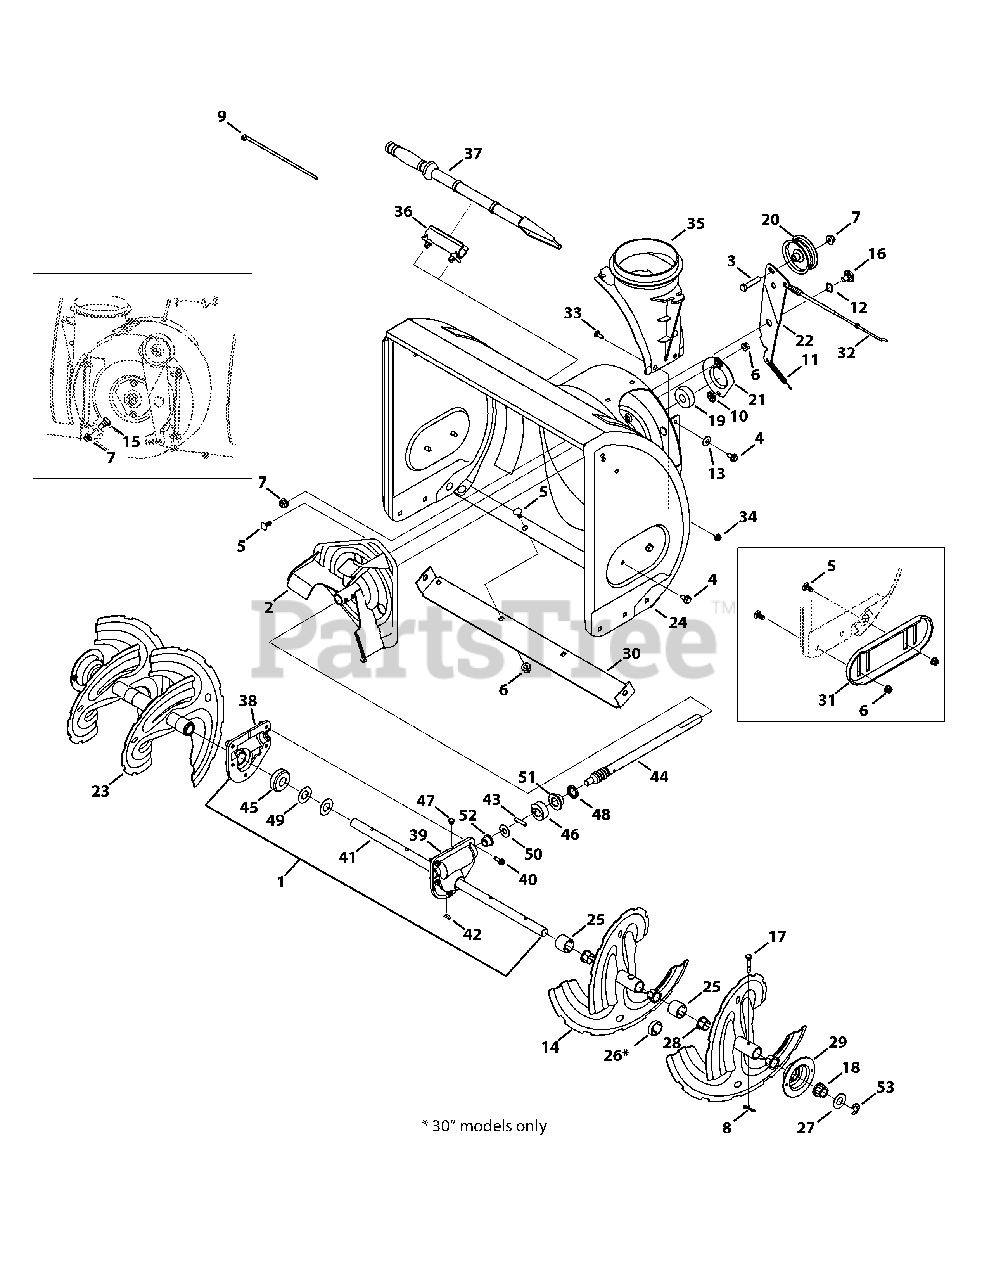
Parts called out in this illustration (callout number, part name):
1	Gearbox Ass'ly, 28", includes 38-52
2	Impeller Assembly, 12" Dia.
3	Hex Head Screw, 3/8-16 x 1.75
4	Screw, 5/16-18 x .750
5	Bolt, Carriage, 5/16-18 x .750
6	Nut, Flange lock, 5/16-18
7	Nut, Flange lock, 3/8-16
8	Bow-Tie Cotter Pin
9	Cable Tie, 7"
10	Nut, Push-on, .25 Dia.
11	Extension Spring, .38 x 4.59
12	Washer, Wave, .625 x .885
13	Washer, Bell, .340 x .872
14	Spiral Assembly, LH
15	Bolt, Shoulder, .496 x .336 x 3/8-16
16	Screw, Shoulder, .625 x .17 x 3/8-16
17	Shear Pin, .25 x 1.50
18	Hex Flange Bearing
19	Bearing, Ball, .75 x 1.85
20	Pulley, Idler, Flat, 2.75
21	Bearing, 1.85 ID
22	Auger Idler Bracket
23	Spiral Assembly, RH
24	Auger Housing Assembly, 28"
25	Spacer, 1.25 x .75 x 1.00
26	Spacer, 1.250 x .75 ID x 3/16 LG
27	Washer, Flat, .76 x 1.49
28	Bushing, Flange, .800 x .910
30	Shave Plate, 2.25 x 27.66
31	Deluxe Slide Shoe
32	Auger Drive Clutch Cable
33	Screw, Carriage, 1/4-20 x .75
34	Nut, Flange lock, 1/4-20
35	Chute Adapter
36	Clean-Out Tool Mount
37	Clean-Out Tool
38	Reducer, RH
39	Reducer, LH
40	Screw, 1/4-20 x 0.750
41	Auger Axle, 28"
42	Key, Hi-Pro, 3/16 x 5/8
43	Dowel Pin, .25 x 1.25
44	Worm Shaft, .75
45	Gear Worm, 20T
46	Collar Thrust, .756 x .600
47	Plug, 1/4 x .437
48	Oil Seal, .75 x 1.131 x .188
49	Washer, Flat, .760 x 1.50
50	Washer, Flat, .51 x 1.12
51	Bearing, Flange, .75 x 1.00 x .59
52	Bearing, Flange, .50 x .75 x .59
53	E-Ring, .750
